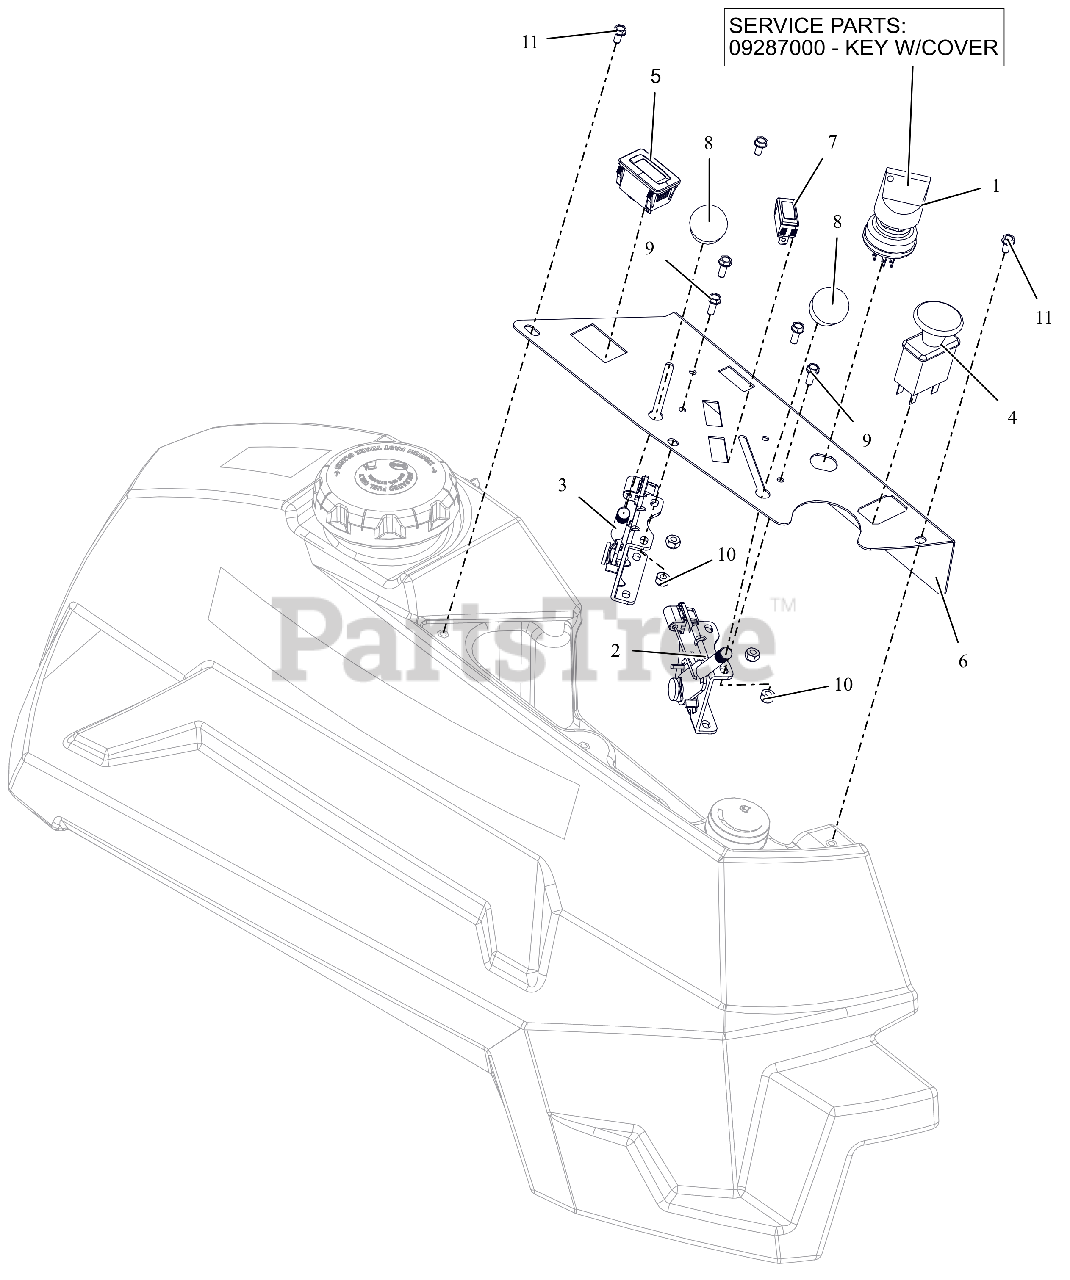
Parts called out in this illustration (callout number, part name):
1	SWITCH, IGNITION
1	KEY, W/ SHIELD
2	CABLE, PRO-CTRL 53.00"
3	CABLE, PRO-CTRL 46.00"
4	SWITCH, CLUTCH
5	HOUR METER
6	PT400 CONTROL PANEL - RED
7	LIGHT, INDICATOR (RED)
8	KNOB-CONTROL-BLACK .38-16X.50
9	BLT, HWH #10-24X.50 ZCC
10	NUT-LK-NYL #10-24 G2 ZCC
11	SCR-MCH 10-24X.38 HWHSTAINLESS
